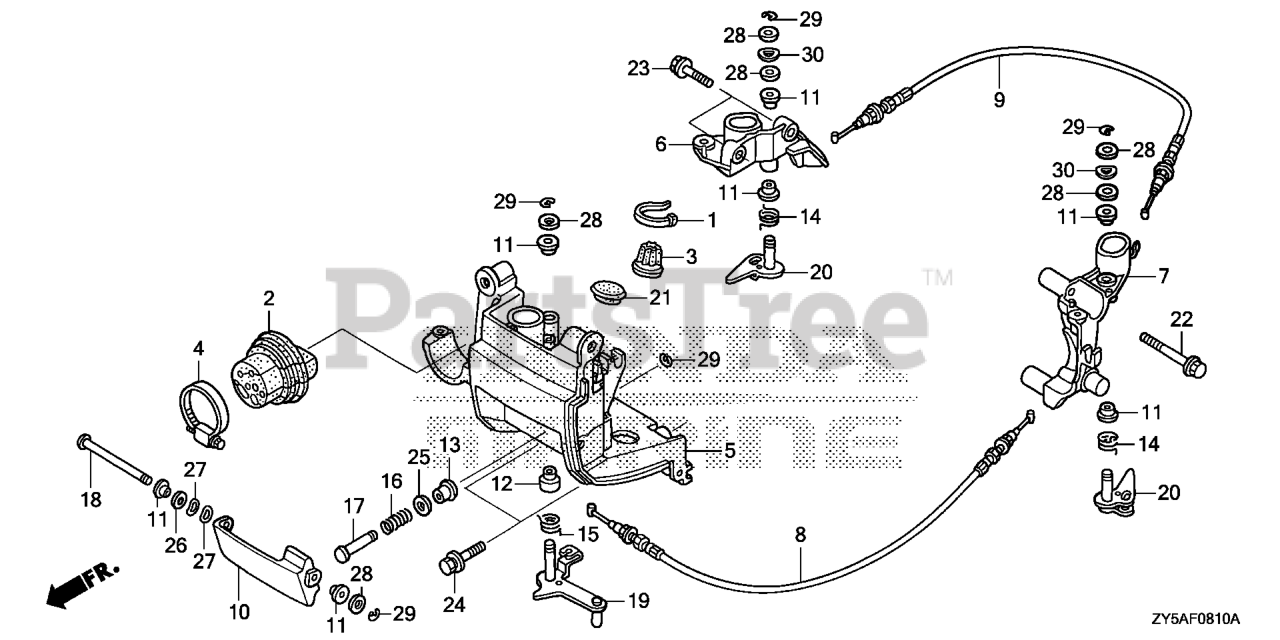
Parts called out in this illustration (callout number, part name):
1	BAND (BLACK 3.5X140)
2	GROMMET, REMOTE CONTROL CABLE
3	GROMMET, CASE (LOWER) (C)
4	BAND, CASE GROMMET (LOWER)
5	BRACKET, FR. COVER (LOWER) *NHB14M* (AQUA MARINE SILVER METALLIC)
5	BRKT,UNDER*NH565*
6	BRACKET, R. SIDE COVER
7	BRACKET, L. SIDE COVER
8	CABLE A, COVER LOCK
9	CABLE B, COVER LOCK
10	LEVER, COVER LOCK *NHB14M* (AQUA MARINE SILVER METALLIC)
10	LEVER, COVER LOCK *NH565* (GRAND PRIX WHITE)
11	BUSH A, COVER LOCK
12	BUSH A, COVER LOCK
13	BUSH B, COVER LOCK
14	SPRING, COVER LOCK HOOK
15	SPRING, COVER LOCK HOOK
16	SPRING, LOCK LEVER RETURN
17	SHAFT, COVER OPEN
18	SHAFT, FR. LOCK
20	LOCK, SIDE
21	CAP, L. SIDE COVER
22	BOLT, FLANGE (8X55)
23	BOLT, FLANGE (6X22)
24	BOLT-WASHER (8X30)
25	WASHER, PLAIN (8MM)
26	WASHER, PLAIN (10MM)
27	WASHER, WAVE (10MM)
28	WASHER, PLAIN (8MM) Use from Frame SN 4800713.
29	E-RING (6MM)
30	WASHER, WAVE (8MM)
